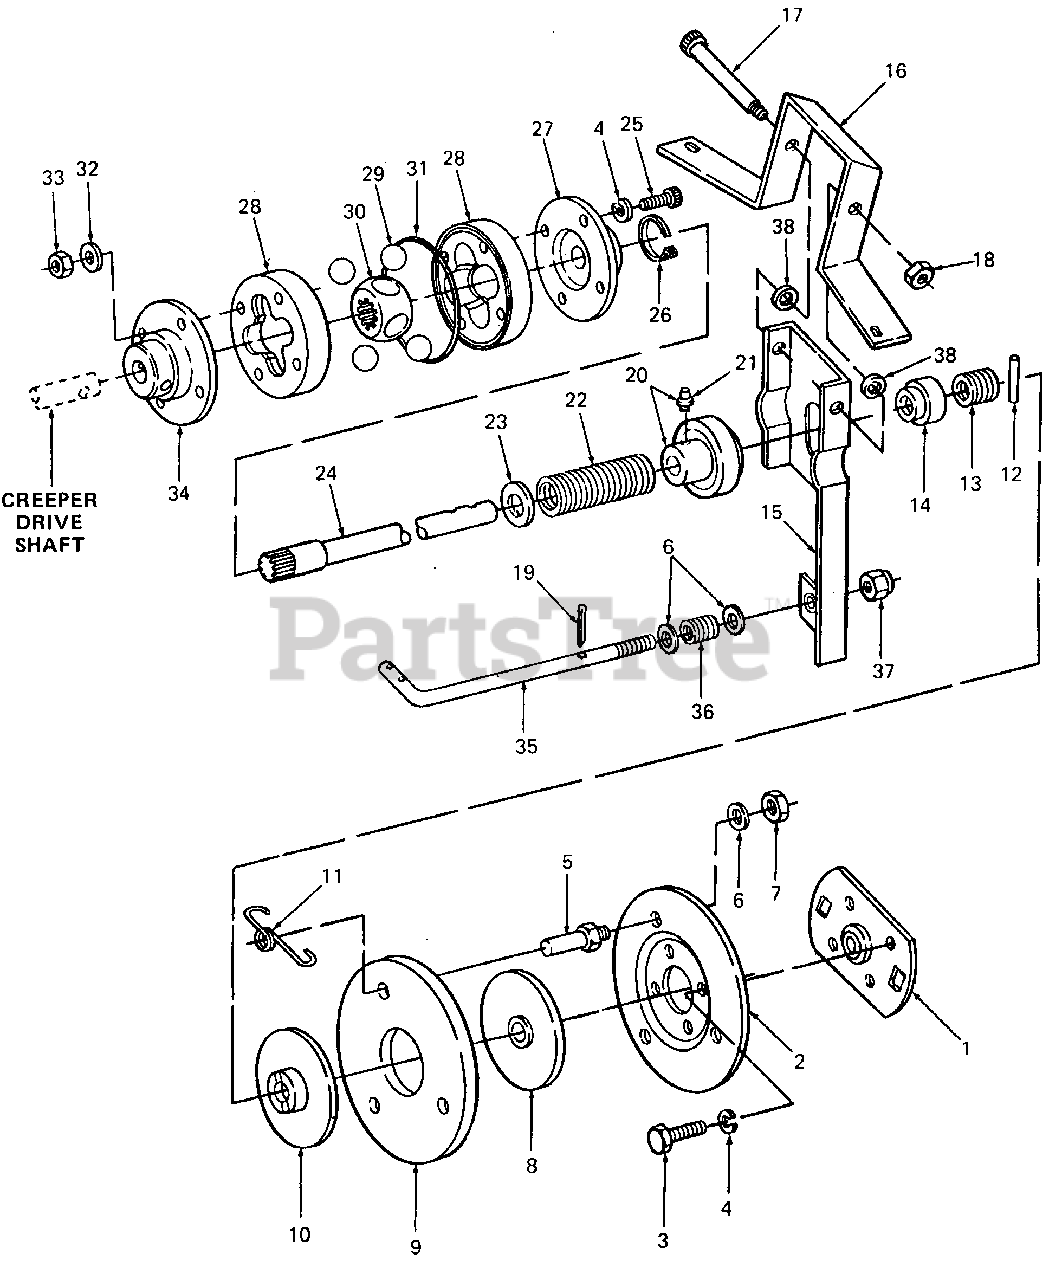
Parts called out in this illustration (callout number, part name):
1	Flange Assy, Drive Shaft
2	Disc, Clutch Driving
3	Screw, Hex Cap, 1/4-20 X .62 Lg GR5
4	Washer, Lock, 1/4
5	Stud, Drive
6	Washer, Flat, .406 X .75 X .063 Thk
7	Nut, Hex Jam, 3/8-16 GR5
8	Hub Assy, Pressure Plate Locating
9	Disc, Clutch Friction
10	Hub Assy, Pressure Plate
11	Spring, Driving Disc
12	Pin, Spiral Spring, 1/4 Dia X 1.50 Lg
13	Spring, Compression, .875 OD X .442 Lg
14	Spacer
17	Screw, Socket Hd Shld, 3/8 X 3.0 Lg 5/16-18 Thrd
18	Nut, Hex Center Lock, 5/16-18 GR5
19	Pin, Cotter, 1/8 Dia X .75 Lg
20	Bearing Assy, Throwout
21	Fitting, Lube
22	Spring, Compression, 1.05 OD X 6.7 Lg
23	Washer, Flat, .635 X 1.0 X .120 Thk
24	Shaft, Drive, 15.12 Lg
25	Screw, Socket Hd Cap, 1/4-20 X 2 .0 Lg
26	Strap, Tie
27	Boot, Coupling
28	Coupling, Drive w/O-Ring Groove
29	Ball, Steel, 5/8 Dia Chrome
30	Hub, Drive
31	O-Ring, 2.489 X .070
32	Washer, Flat, .25 X .62 X .052 Thk
33	Nut, Hex Patch Lock, 1/4-20
34	Adapter w/Hole
35	Rod, Clutch Release
36	Spring, Compression, .50 OD X 3.75 Lg
37	Nut, Hex Insert Lock, 3/8-24 GR5
38	Washer, Flat, .406 X .75 X .063 Thk
